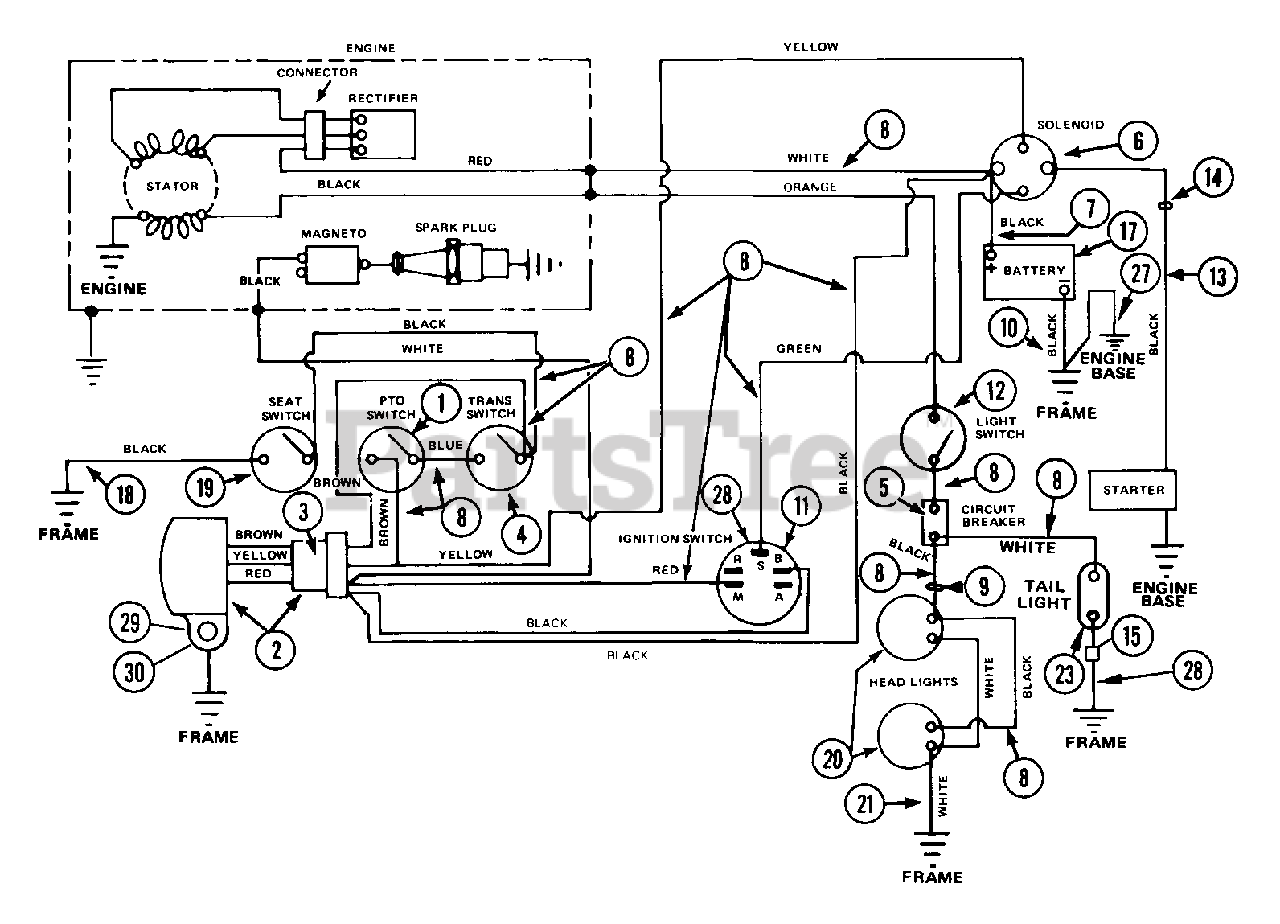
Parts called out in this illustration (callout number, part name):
1	SWITCH INTERLOCK
2	MODULE
3	CONNECTOR
4	SWITCH-NEUTRAL START N.O.
5	CIRCUIT BREAKER
6	SOLENOID
7	GROUND CABLE
8	WIRE HARNESS
9	CLAMP LOOP
10	GROUND CABLE
11	IGNITION SWITCH AND KEY ASSEMB
12	LIGHT SWITCH
13	GROUND CABLE
14	TIE DOWN
15	WIRE CLIP
17	BATTERY
18	GROUND WIRE
19	SWITCH SEAT
20	HEAD LIGHT
21	GROUND WIRE
22	TAIL LIGHT WIRE
23	TAIL LIGHT
23	TAIL LIGHT LENS
27	GROUND CABLE
28	GROUND WIRE
29	SCR-MCH 10-24X.62 SLRH PL
30	NUT-KEPS 10-24 PL
30	WSHR-LK .312X.097 PL HVY
30	NUT-JAM .312-24 PL
30	WSHR-LK 10X.047 MED PL
30	NUT 10-32 PL
